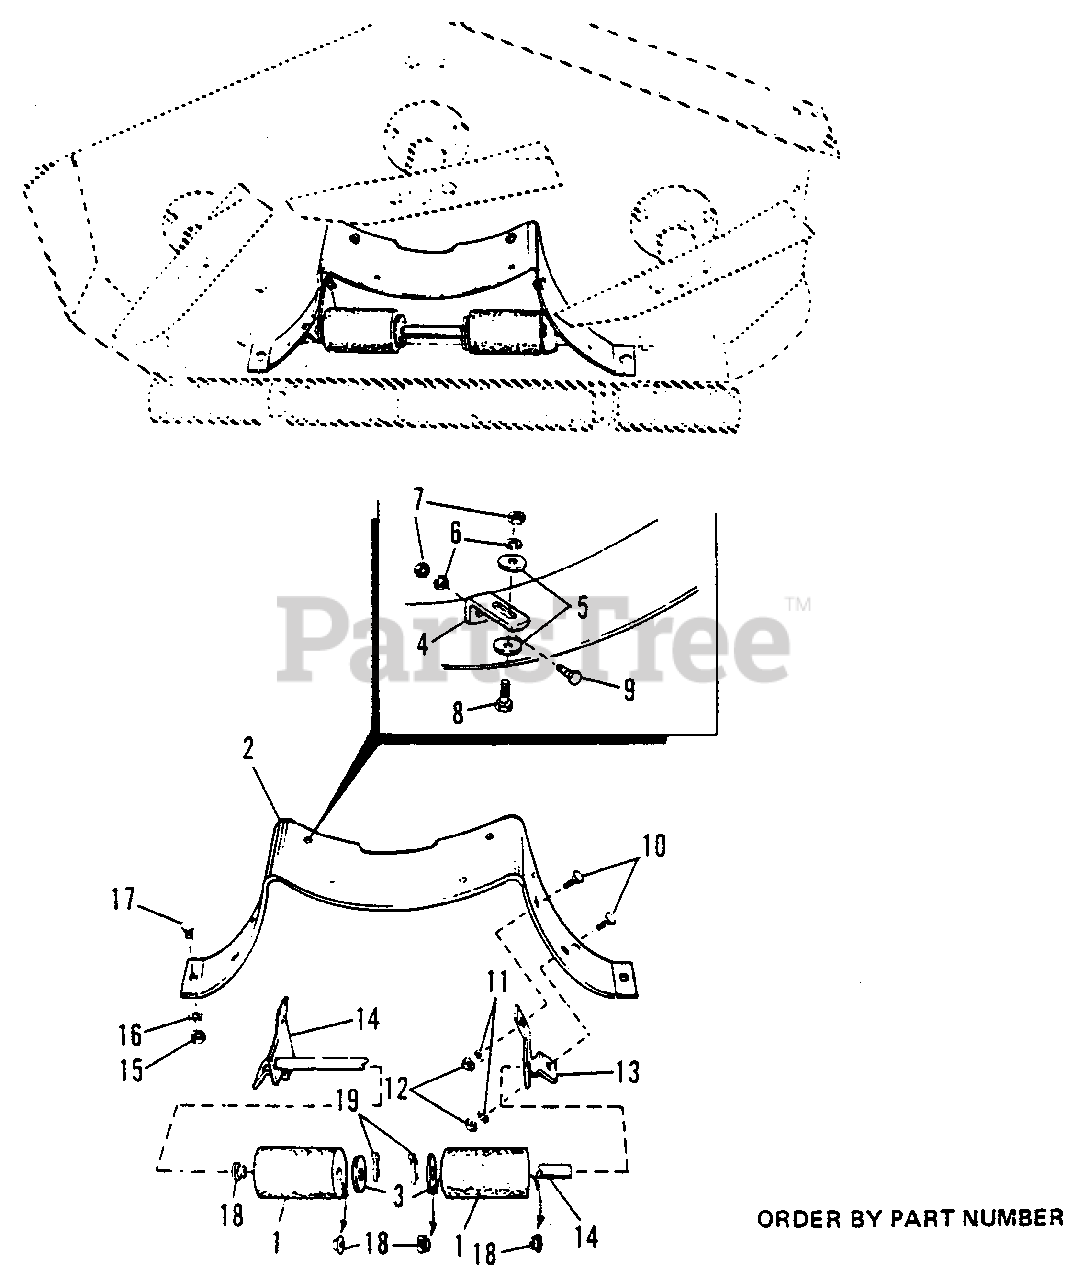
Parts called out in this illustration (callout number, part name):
1	Roller W/Bushing
4	Clip Baffle
5	Plain Washer, 1/4"
6	Lockwasher, 1/4"
7	Full Hex Nut, 1/4"-20 N.C.
8	Hex Capscrew, 1/4"-20 x 5/8"
9	Screw, Recessed Hex Self Tapping, 1/4" 20 N.C. x 7/8"
10	Carriage Bolt, 5/16"-18 x 3/4"
11	Lockwasher, 5/16"
12	Full Hex Nut, 5/16"-18
13	Lower Roller Bracket, L.H.
14	Bracket & Shaft Assembly
15	Full Hex Nut, 3/8"-16 N.C.
16	Lockwasher, 3/8"
17	Carriage Bolt, 3/8"-16 x 3/4"
19	Cotter Pin, 3/16" x 1"
